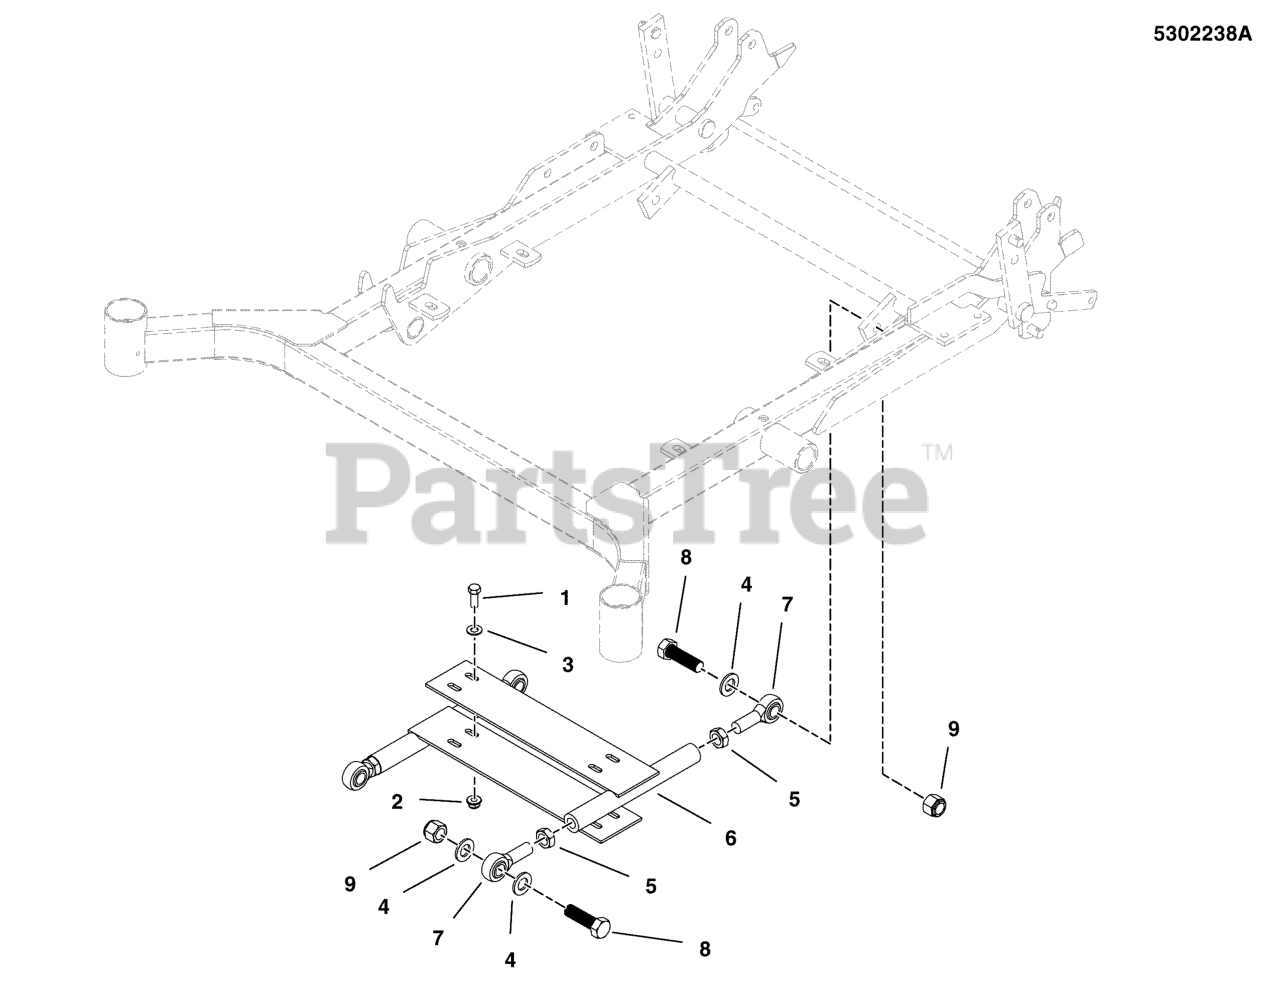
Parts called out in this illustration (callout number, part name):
1	BOLT, 3/8-16 X 1" GD5 CZ
2	NUT, 3/8-16 HEX SERRATED FLANGE
3	WASHER, 3/8 SAE
4	WASHER, 5/8 SAE
5	NUT, 5/8-18, HEX JAM
6	WELD, DECK STABILIZER - RED
7	BALL JOINT, 5/8-18, MALE
8	BOLT, HEX, 5/8-11 X 2-1/2, GD5, CZ
9	NUT, 5/8-11 HEX NYLON LOCK
